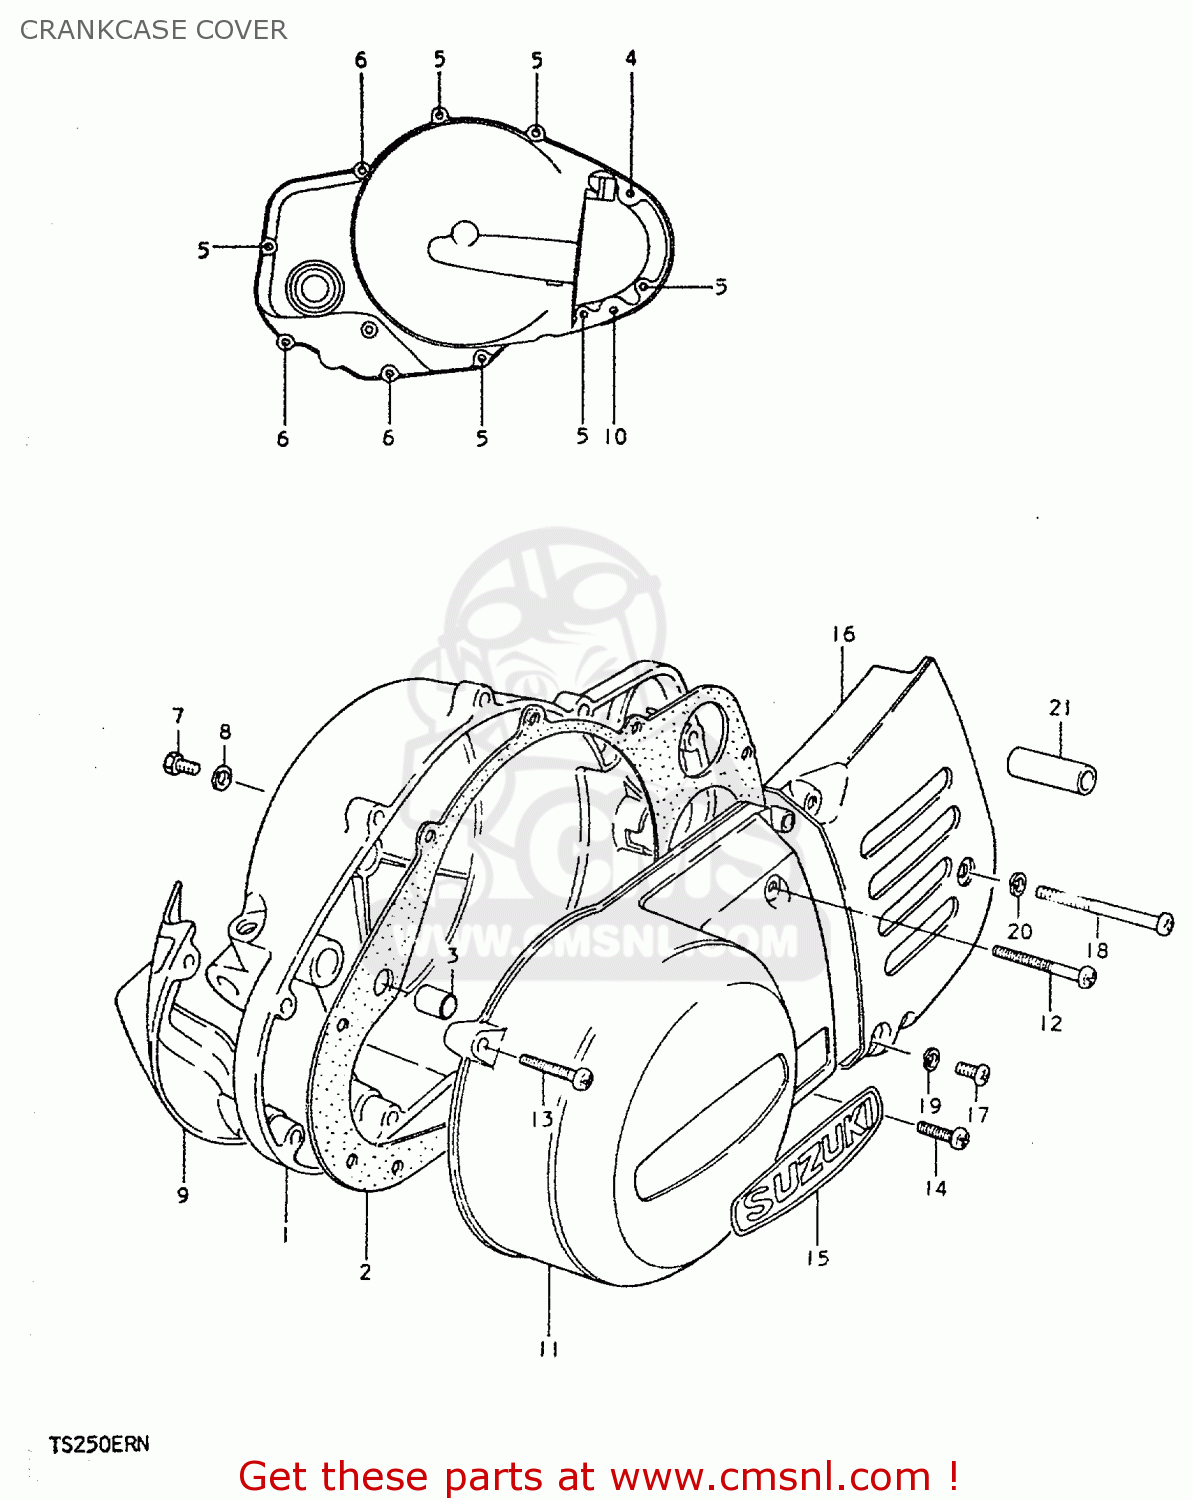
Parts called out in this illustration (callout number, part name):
1	COVER,CLUTCH
2	GASKET,CLUTCH COVER (MCA)
3	PIN
4	SCREW 6X30
5	SCREW
6	SCREW
7	SCREW(6X10)
8	GASKET(6.2X11X1) (NAS)
9	COVER,CLUTCH RELEASE A
10	SCREW
11	COVER,MAGNETO
12	SCREW (6X35)
13	SCREW
14	SCREW
15	EMBLEM,MAGNETO COVER
16	COVER,SPROCKET
17	SCREW
18	SCREW 6X60
19	LOCK WASHER
20	LOCK WASHER
21	CUSHION
